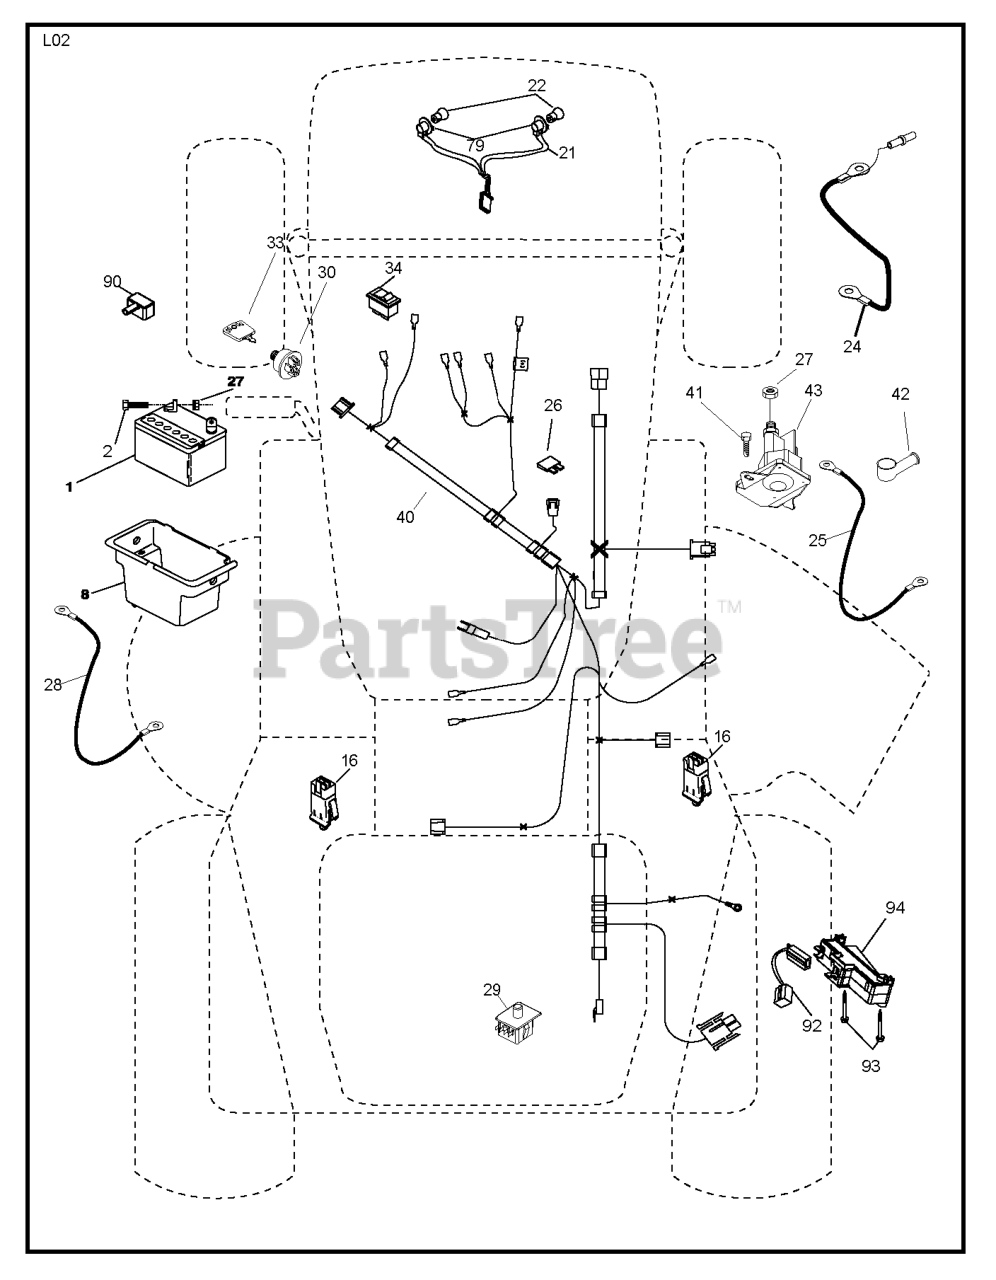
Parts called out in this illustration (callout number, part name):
1	Battery 12 Volt 25 Amp
2	BOLT.HEX.1/4.X.3/4.DICHROMATE
8	BOX.BATTERY.FENDER
16	SWITCH INTERLOOK PUSH-IN
21	HARNESS.W/LIGHT SOCKET
24	CABLE.GROUND.REAR.BTRY.8GA.44"
25	CABLE.STARTER.6GA.11"RED
26	FUSE 20AMP
27	NUT
28	CABLE GROUND 6 GA. 12" BLACK
29	SWITCH.SEAT.DP W/RAMPS
30	SWITCH.IGN.DELTA.W.LGH.ROS
33	KEY.CHAIN.BLISTER.PACK.GEN.INT
40	HARNESS.IGN.CABLE.REG.
41	BOLT
42	TERMINAL COVER
43	SOLENOID.W/BRASS.PLUNGER
79	BULB HOLDER ASM.
90	COVER TERMINAL
92	HARNESS.PIGTAIL.CONSLE
93	SCREW.PLASTITE
94	MODULE.REVERSE.ROS
